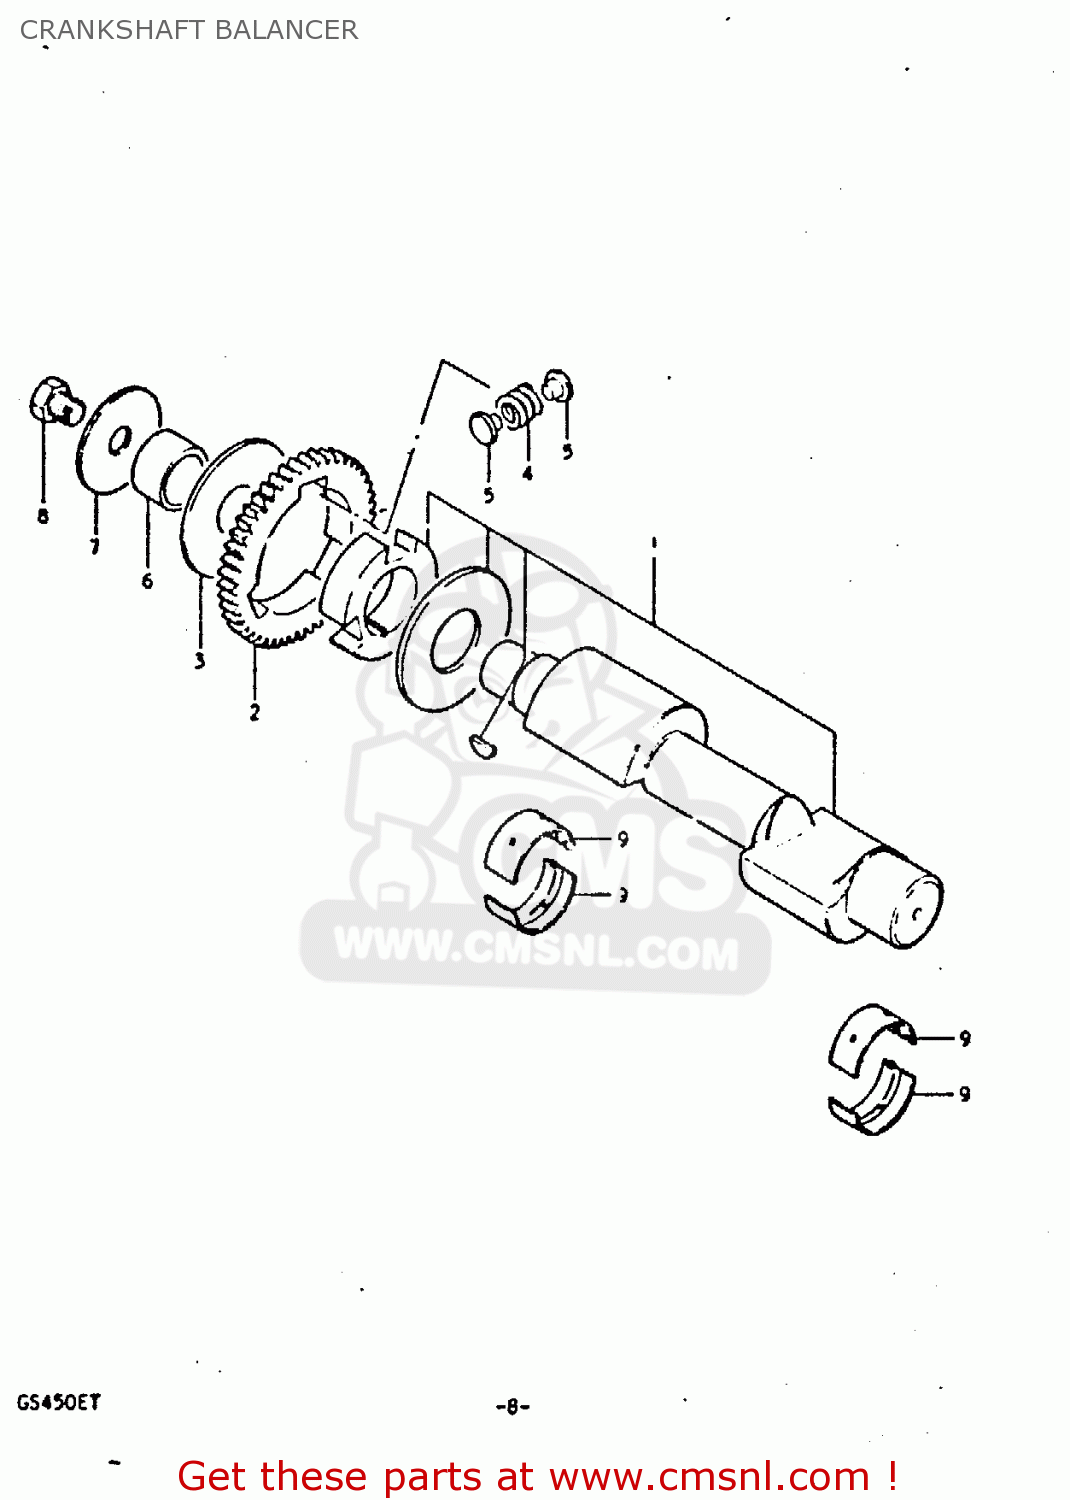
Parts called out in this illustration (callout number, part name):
1	BALANCER,CRANKSHAFT
2	GEAR,CRANK BALANCER DRIVE
3	WASHER
4	SPRING
5	PIN
6	SPACER
7	WASHER(12X50X3)
8	BOLT
9	METAL CRANKSHAFT
